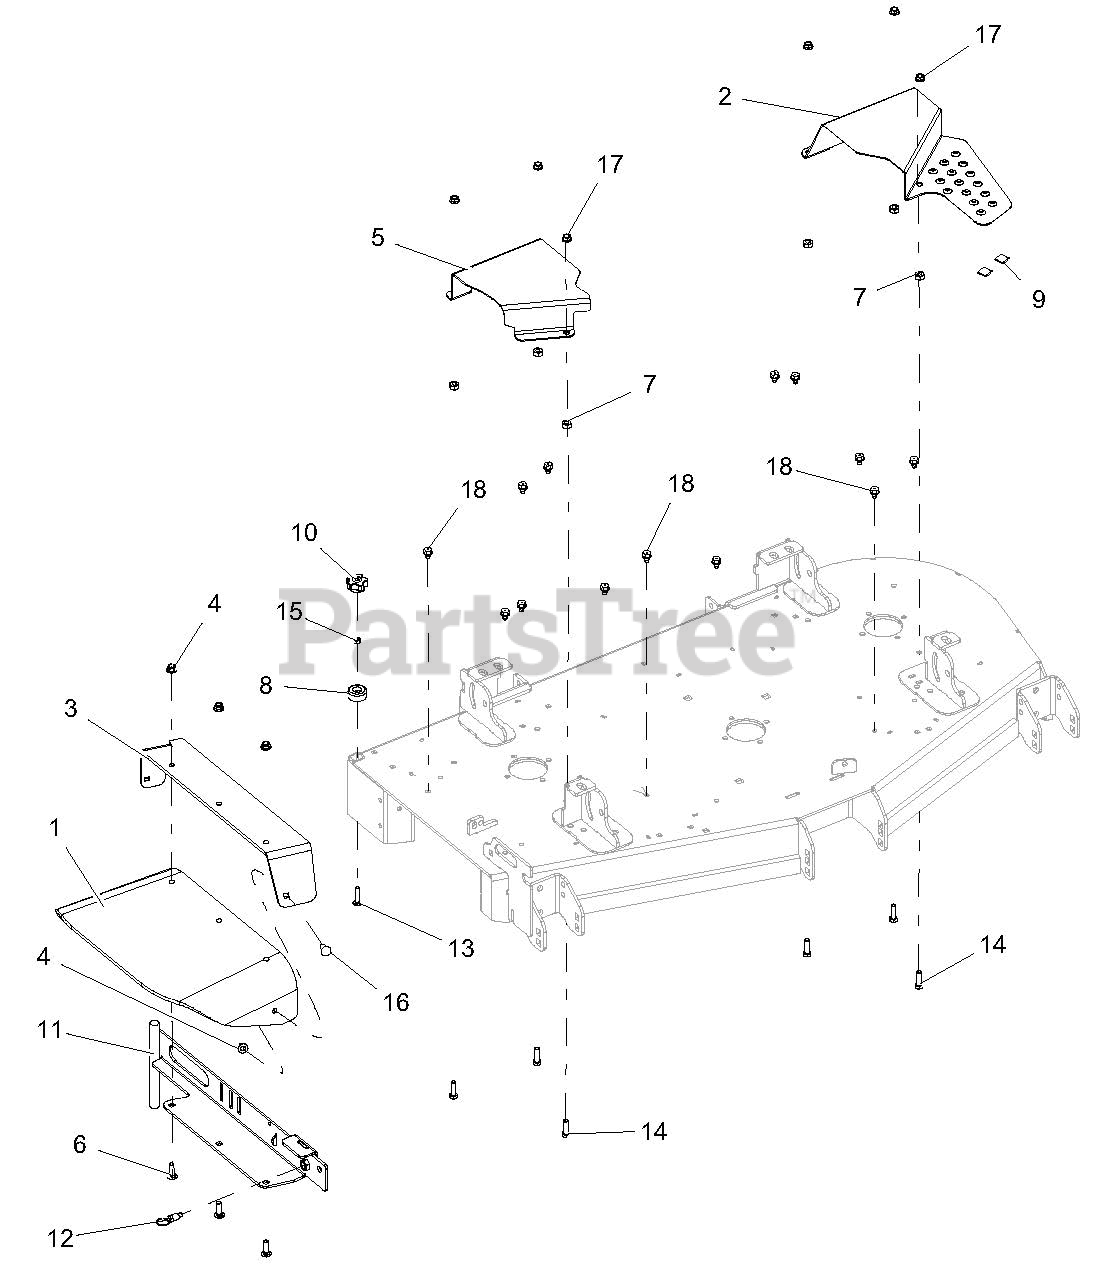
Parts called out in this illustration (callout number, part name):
1	CHUTE, RUBBER DISCHARGE
2	GUARD, 52" LH DECK BELT
3	DISCHARGE CHUTE SUPPORT W/SAFETY DECAL-RED
4	NUT-LK-NYL-FLG .38-16 YWZC
5	GUARD, 48"-52" RH DECK BELT-RED
6	BLT-RDHDSQNK .38-16X1.25 G5 YWZC
7	NUT-HEAVY HEX .38-16 YWZC
8	BUMPER, RECESSED 1.50 X .63 W/.31 HOLE
10	KNOB, CLAMPING
11	WLDMT, 52"-60" DISCH CHUTE MTG-RED
12	PULL PIN,.50-13THDX.310 PLNGR
13	BLT-RDHDSQNK .31-18X1.50 G5 YWZC
14	BLT-HEX .38-16X1.25 GR5 YWZC
15	NUT-LK-CTR .31-18 YWZC
16	BLT-RDHDSQNK .38-16X1.00 G5 YWZC
17	@NUT-SPNLK-FLG .375-16 YWZC
18	SCR-TAP .38-16X.50 HWH TR YWZ
